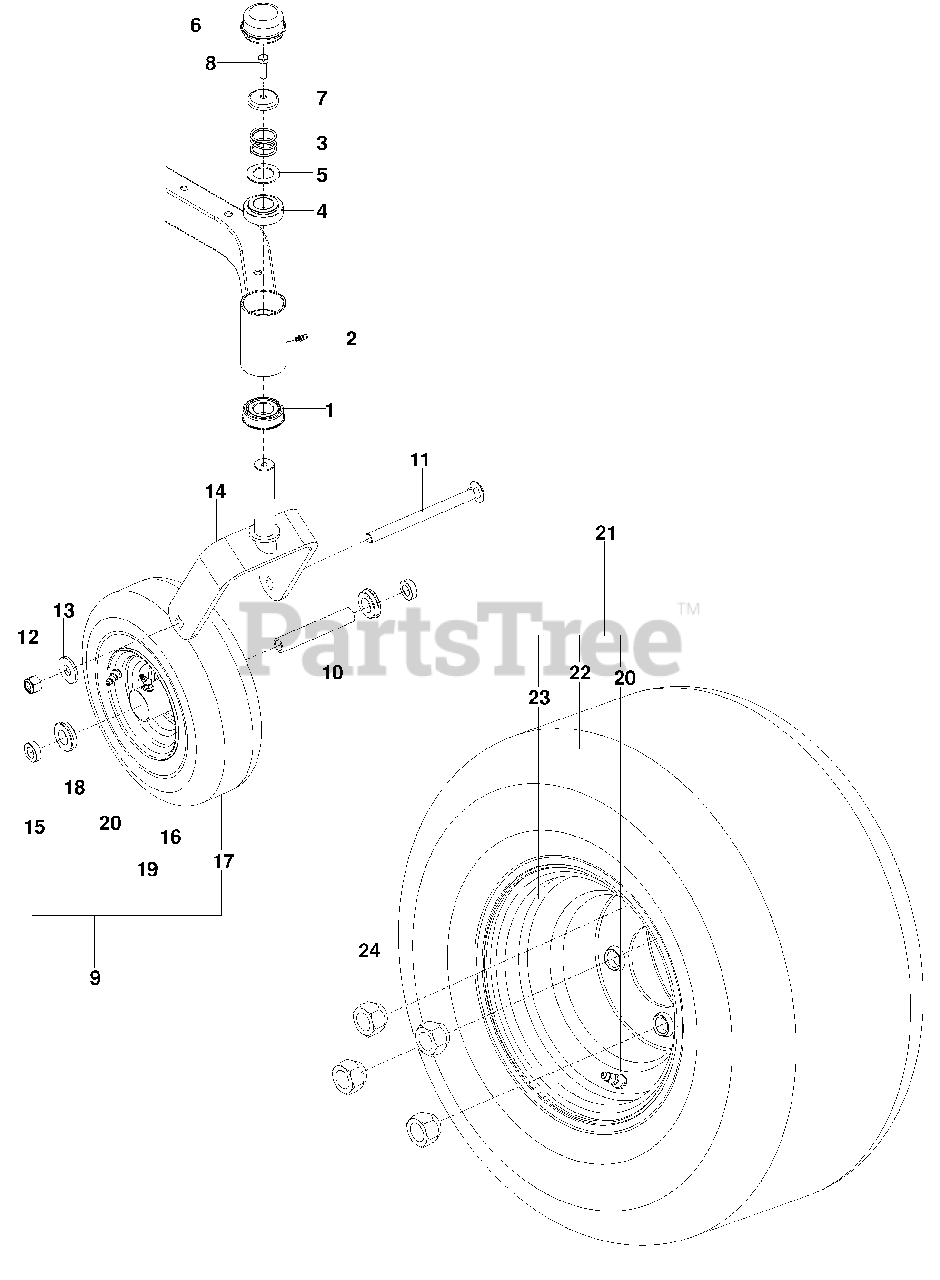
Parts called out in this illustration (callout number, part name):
1	BEARING, FLANGED
2	ZERK 3/16 DRIVE
3	SPRING, CASTER
4	BUSHING, CASTER
6	GREASE CAP
7	PLUG, CASTER
8	HCS 5/16-18 x 1
9	CASTER TIRE ASSY
11	RHSNB 1/2-13 x 6 1/2
12	NUT 1/2 HEX CNTRLK
13	WASHER 1/2 FLAT
14	YOKE, ORG
15	SPACER 5/16
17	CASTER TIRE, 410/350 4 PLY
18	BEARING, FLANGED
19	ZERK
20	VALVE STEM
21	WHEEL ASSY 20 x 8 966047501, 966038201
22	TIRE, REAR 20 x 8
23	RIM 8 x 7 w/ .8" OFFSET
24	NUT 1/2 LUG
